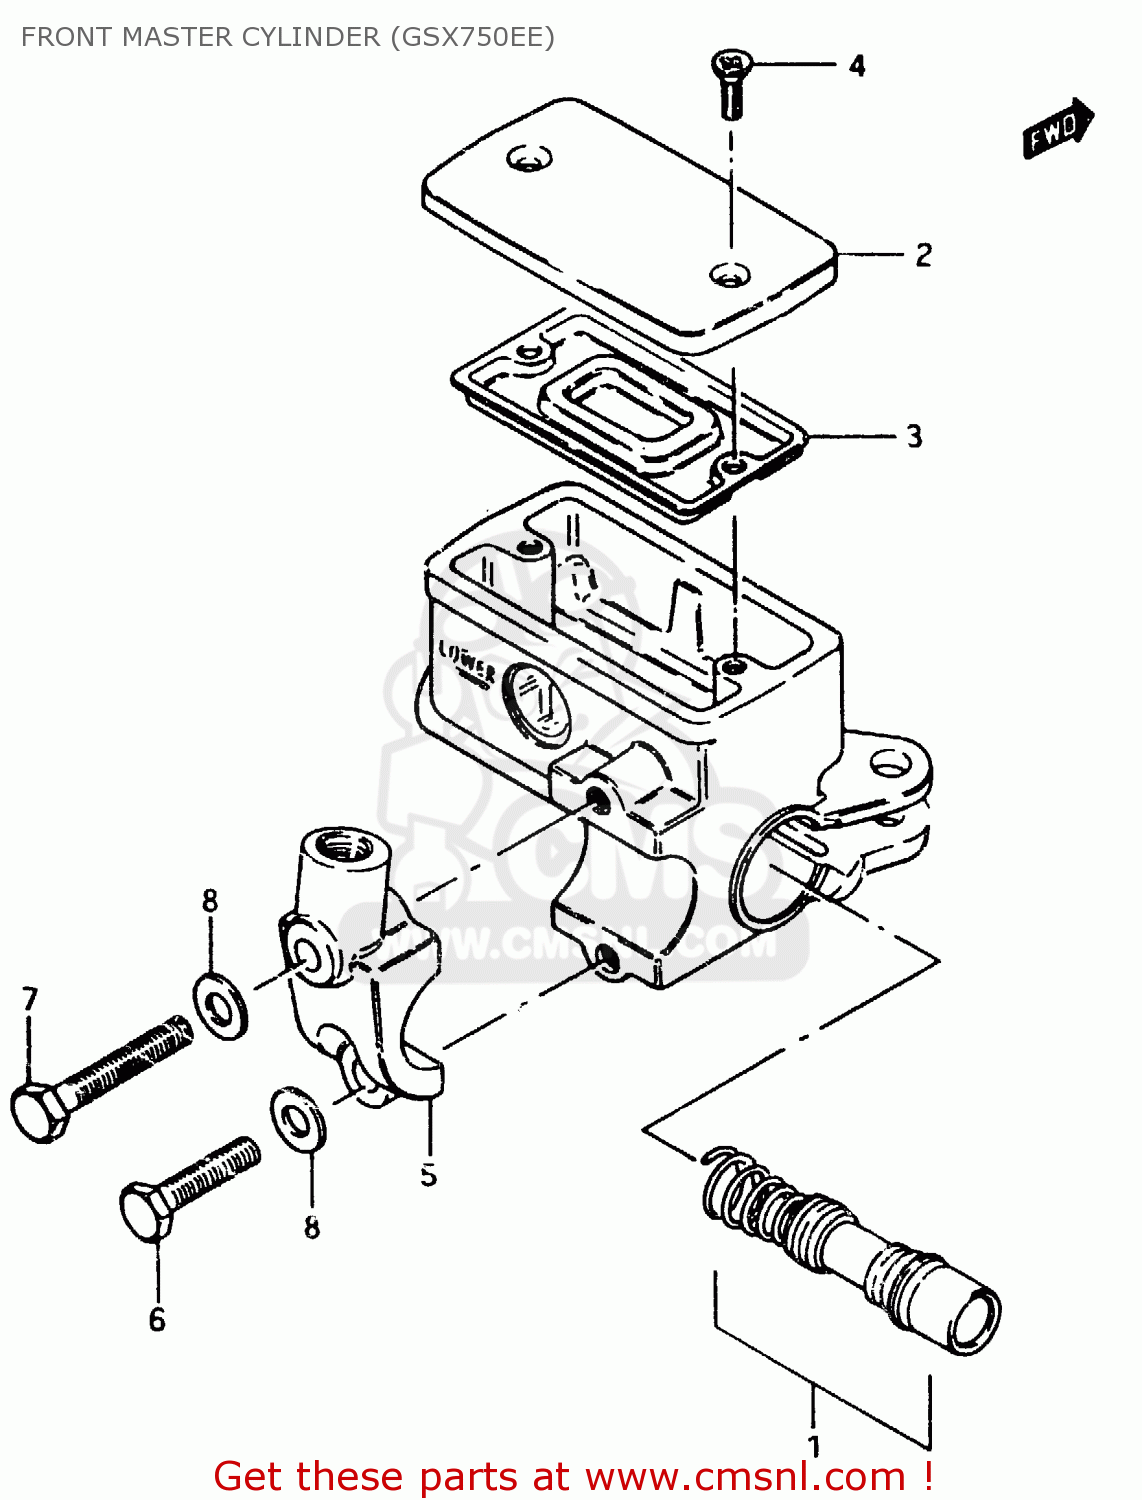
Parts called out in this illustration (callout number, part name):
1	PISTON & CUP SET
2	CAP
3	4
4	SCREW
5	HOLDER
6	BOLT
7	BOLT 6X40
8	WASHER
